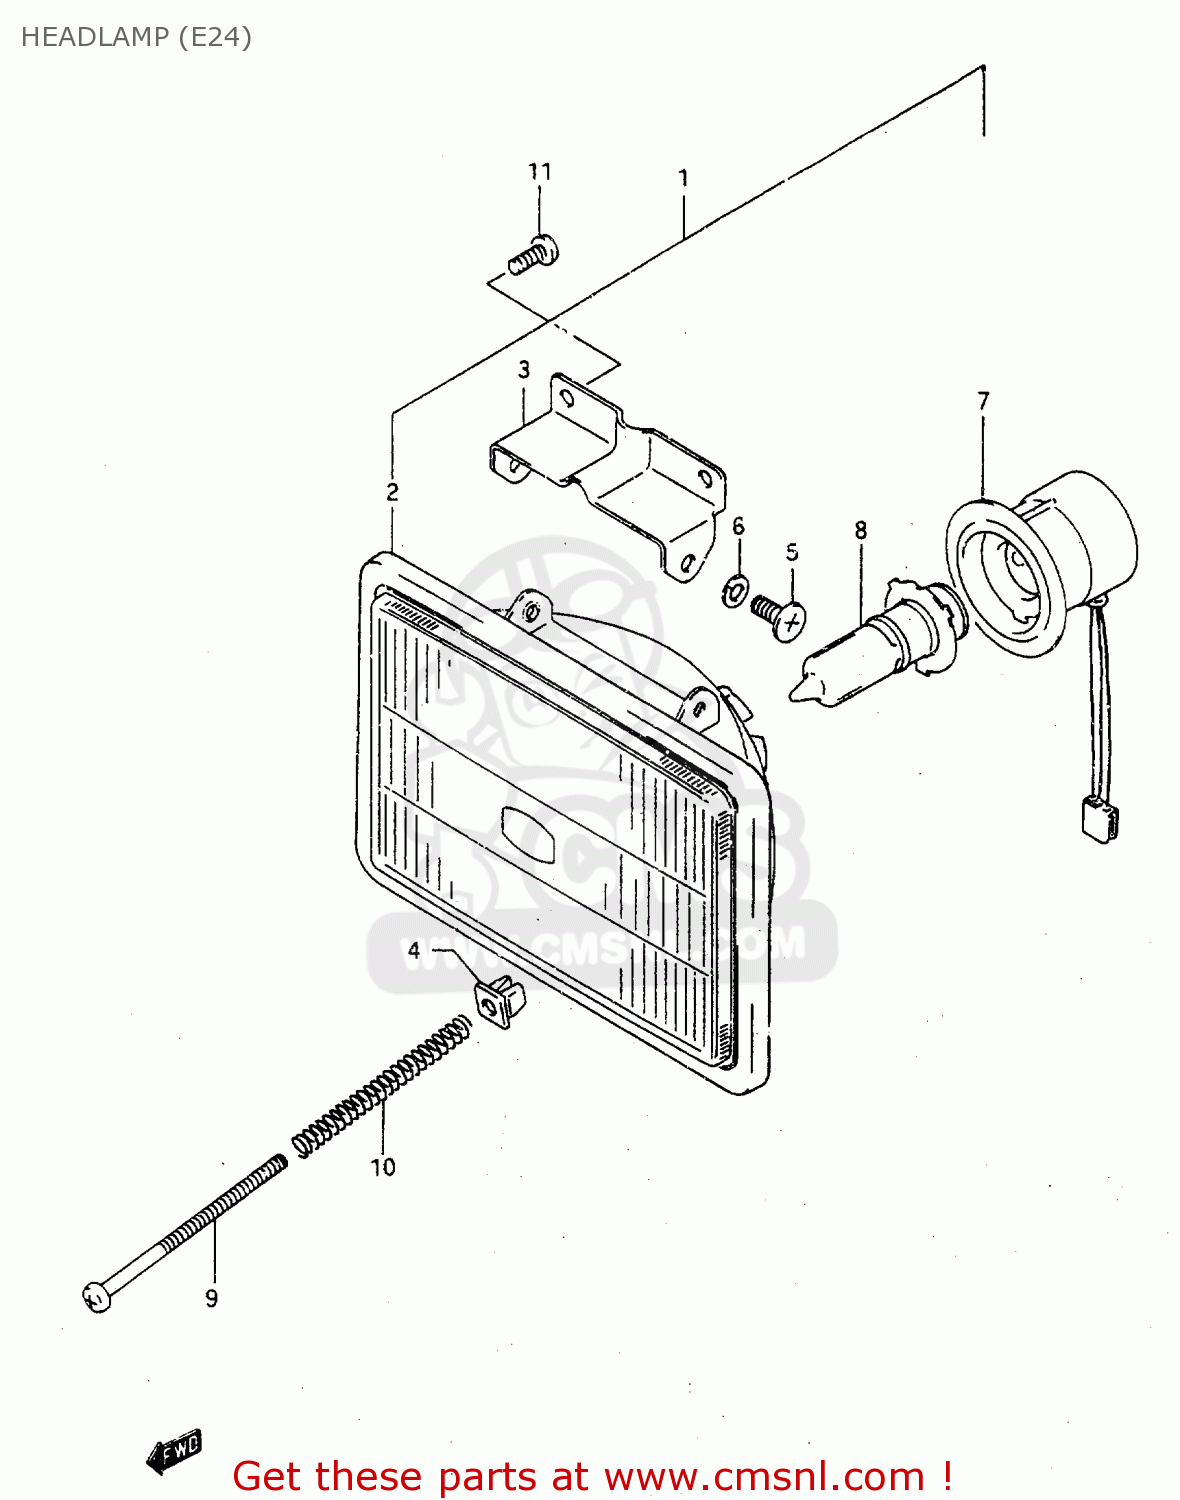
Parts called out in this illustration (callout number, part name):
1	HEADLAMP ASSY
2	UNIT, LAMP
3	BRACKET,LAMP
4	NUT,HEADLAMP ADJUSTER
5	SCREW
6	LOCK WASHER
7	SOCKET
8	BULB(12V35/36.5W)
9	SCREW,HEADLAMP ADJUST
10	SPRING,HEAD LAMP ADJUSTER
11	SCREW
